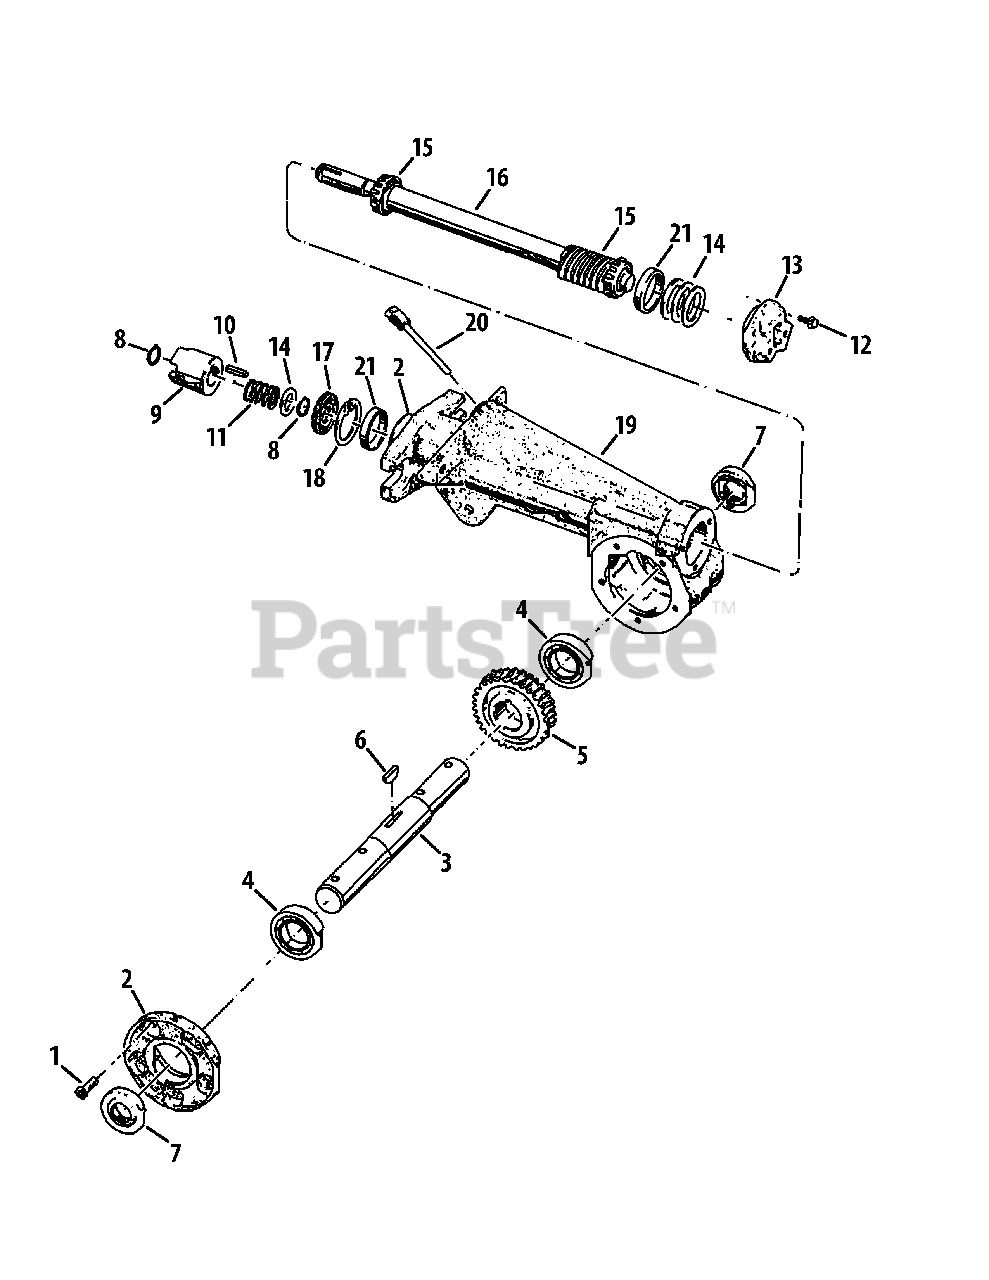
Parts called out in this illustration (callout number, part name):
1	Self-Sealing Screw, 1/4"-20 x 5/8"
2	Tiller Housing Cover
3	Tine Shaft
4	Ball Bearing
5	Worm Gear
6	Woodruff Key
8	External Retaining Ring
9	Dog Clutch
10	Key, 3/16" x 1"
11	Spring
12	Self-Sealing Screw, 1/4"-20 x 7/8"
14	Flat Washer, 175 x 15 x 062
14	Flat Washer, 175 x 15 x 005
14	Flat Washer, 175 x 15 x 03
14	Flat Washer, 175 x 15 x 01
15	Cone Bearing
18	Retaining Ring
19	Attachment Housing
20	Oil Dipstick
21	Cup Bearing
